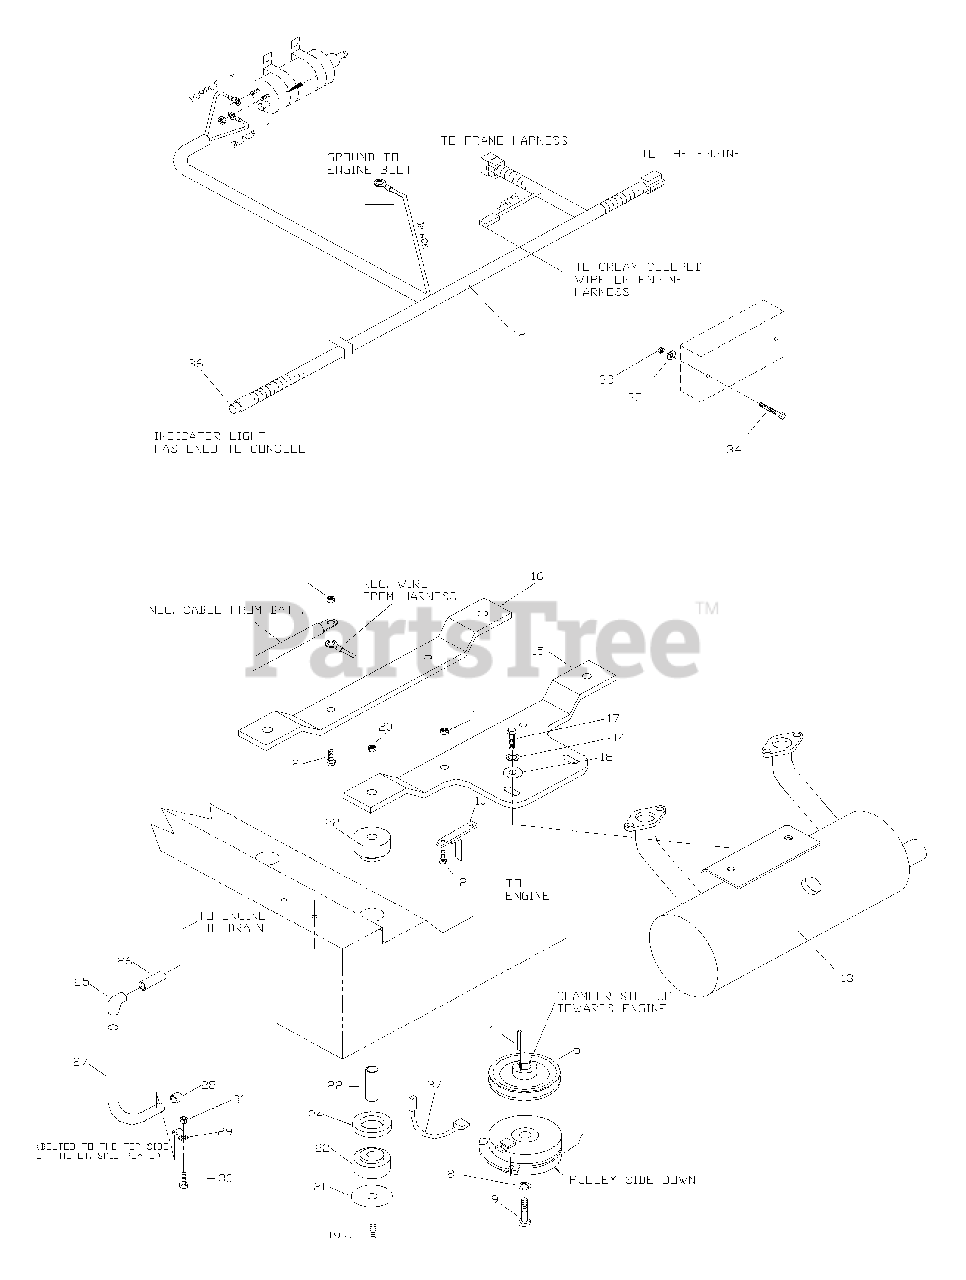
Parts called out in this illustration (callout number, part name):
1	NUT 5/16 LOCK
2	HCS 5/16 X 1.75
4	KEY 1/4 SQ
8	7/16 LOCK WASHER
9	HCS 7/16F X 25
10	CLUTCH TIE DOWN
12	EFI HARNESS
13	EFI MUFFLER
14	5/16 LOCK WASHER
15	REAR ENGINE MT
16	ENGINE MOUNT
17	HCS 5/16 X 10
18	5/16 FLAT WASHER
19	HCS 1/2 X 3.25
20	NUT 1/2 NYLOC
21	ISOLATOR WASHER
24	ISOLATOR SPACER
25	90 DEG ELBOW
26	PIPE 3/8 X 1.5 NPT
27	OIL DRAIN HOSE
30	HCS 1/4 X 3/4
31	NUT 1/4 LOCK
32	SCREW SELF TAP
33	NUT #10 NYLOC
34	SCREW #10 X 2.0
35	#10 WASHER
36	INDICATOR LAMP BULB
37	CLUTCH PIGTAIL
